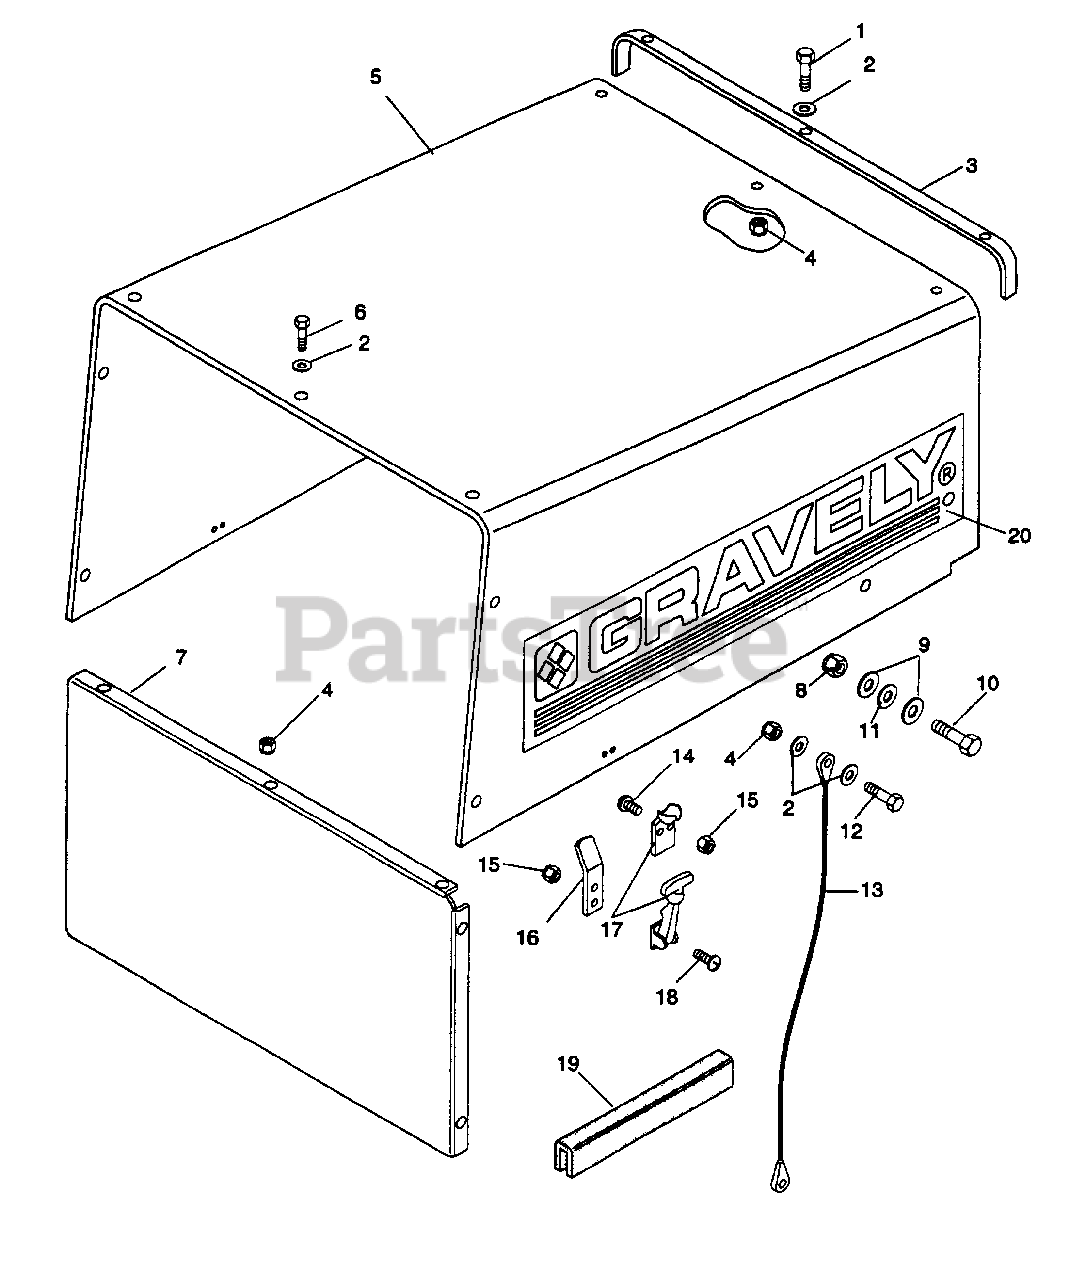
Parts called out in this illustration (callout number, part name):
1	BLT-HEX .25-20 X .75 PL GR 5
2	WSHR-FL-STL .281 X .625 X .065
3	BR, HOOD
4	NUT-LK-NYL .250-20 PL
6	BLT-HEX .25-20 X .63
7	PANEL, HOOD
8	NUT-LK-NYL .375-16 PL
9	WSHR-FL-STL .406 X .812 X .065
10	BLT-HEX .380-16 X .875
11	WSHR-FL-NY .375 X .75 X .060
12	BLT-HEX .25-20 X .875
13	CBL, HOOD
14	SCR-MCH 10-24 X .50 PHD
15	NUT-LK 10-24 NY PL
16	PLT, GUIDE
18	SCR-MCH 10-24 X .750 PHD
19	STRIP, COWL
20	GRAVELY NAME/LOGO/STRIPE DECAL
NS	DECAL, E-SYSTEM WARNING
NS	DECAL, MAINTENANCE
